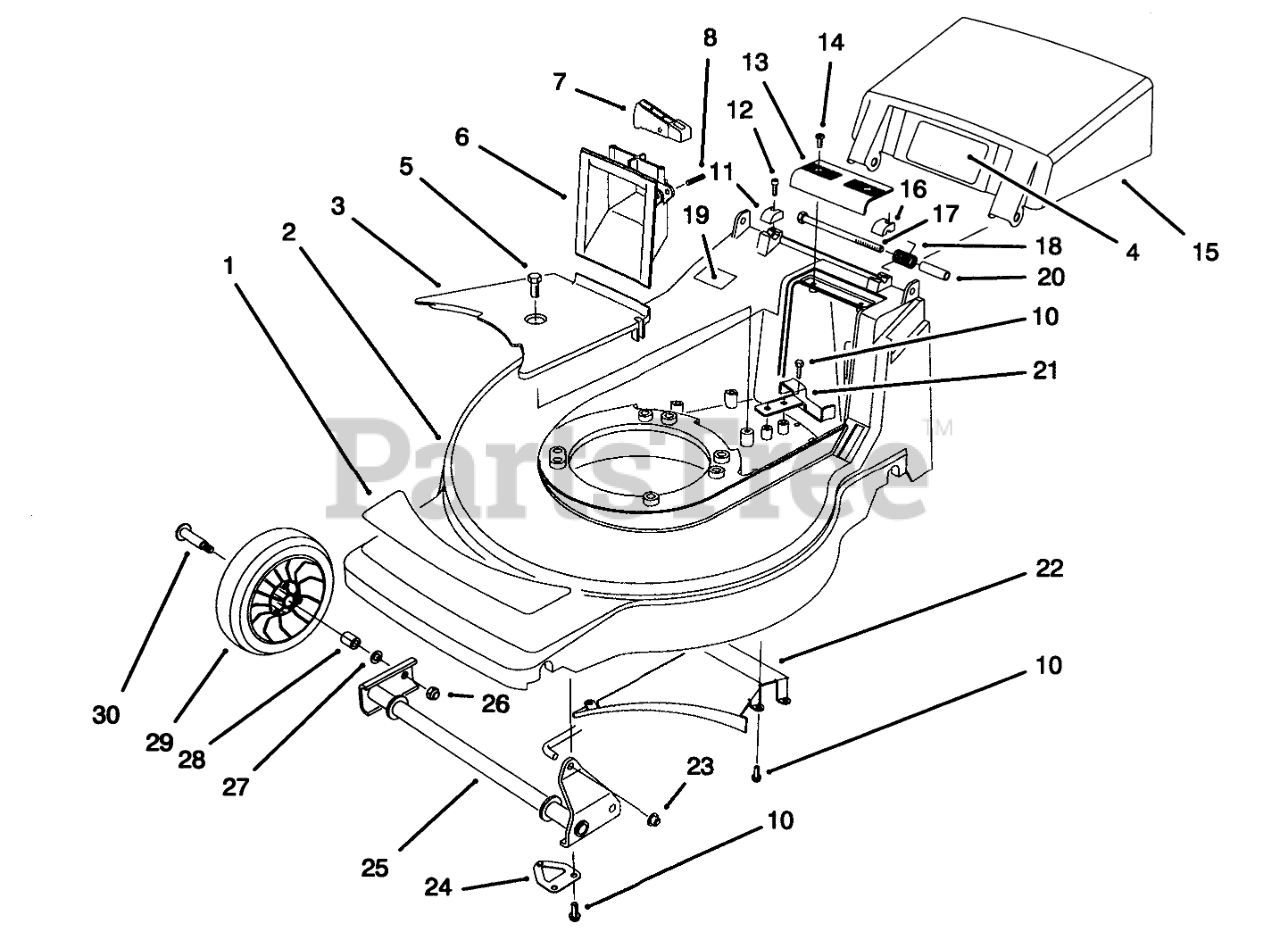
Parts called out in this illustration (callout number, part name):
1	DECAL - DECK 48 CM
2	HOUSING W/DECAL RED
3	BELT COVER
4	DECAL-DANGER
5	SCREW-HWHTF
6	GRIP - LOWER
7	TRIGGER - HOC
8	PIN-SPIRAL
10	SCREW-HWH
11	CAP-HINGE BOLT, RH
12	SCREW-HSH
13	GRIP-UPPER
14	SCREW-PPH, PLASTITE
15	Door Discharge
16	CAP-HINGE BOLT, LH
17	SCREW-HH
18	SPRING-DOOR
19	Decal-Noise
20	SPACER-DOOR
21	REAR BELT GUIDE
22	Ramp-Discharge
23	NUT-PUSH
24	SHAFT RETAINER ASM
25	FRONT PIVOT WA
26	NUT-LOCK, NI
27	WASHER
28	BUSHING
29	Wheel & Tire Assembly (Incl. Ref. #28)
30	BOLT-WHEEL
